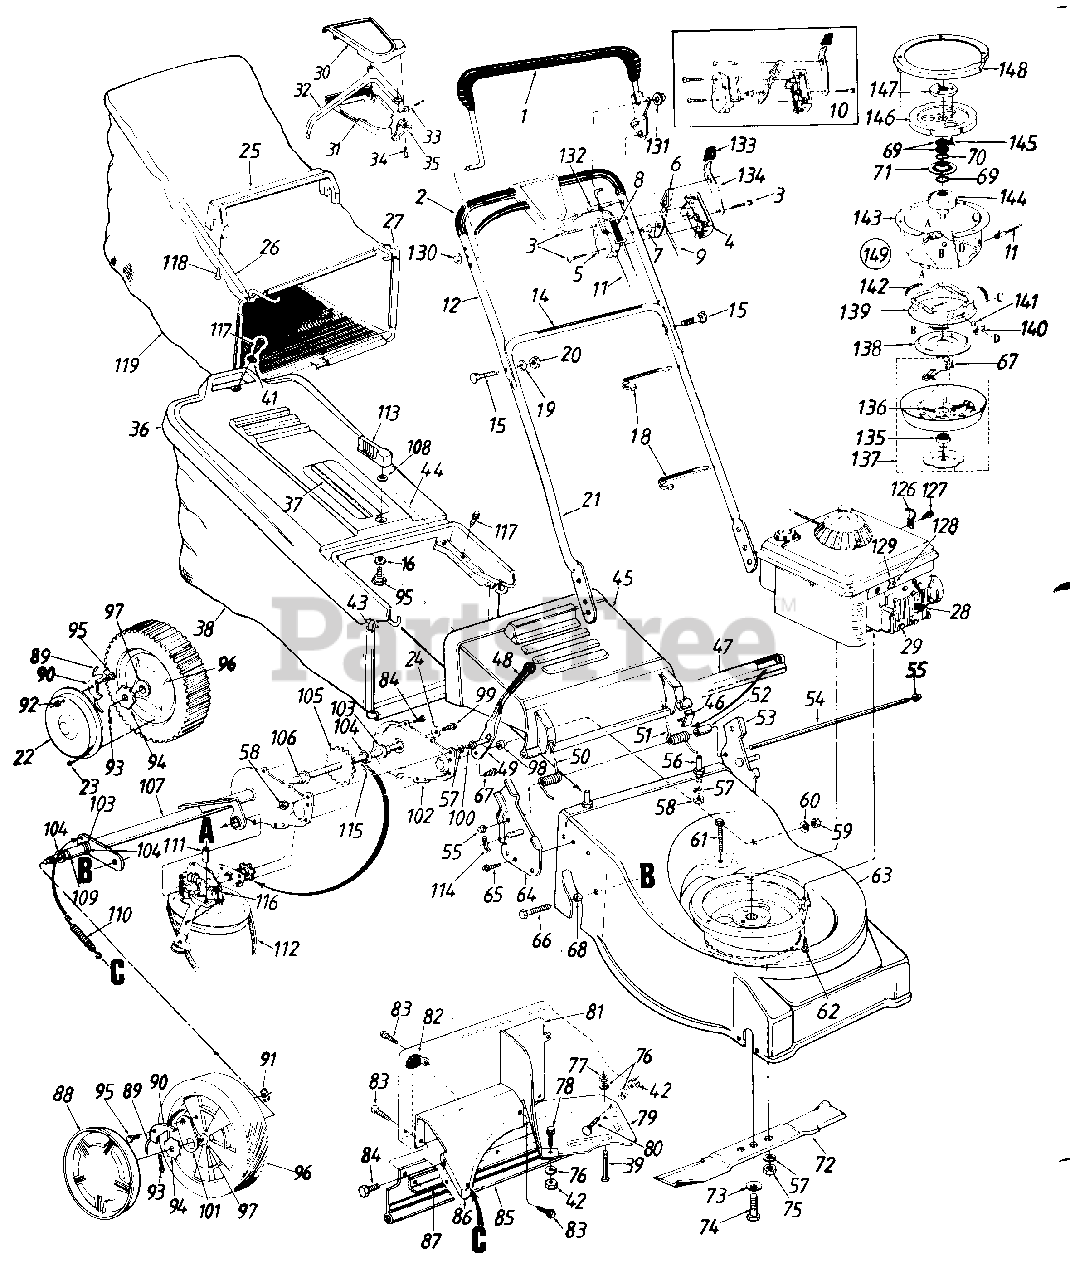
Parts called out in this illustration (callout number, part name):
1	Control Handle Ass'y.
3	Truss Mach. B-Tap Scr. #12 x 1.5" Lg.
4	Control Panel Half
5	Clutch Panel Half
6	Throttle Control Lever
7	Control Disc Pin
8	Control Label-Throttle
9	Throttle Wire-58" Lg.
10	Control Housing Comp.
11	Control Cable-52" Lg.
12	Upper Handle (Painted)
14	Instruction Label-Handle
15	Curved Carriage Bolt 5/16-18 x 1.38" Lg.
16	Bowed Washer
18	Cable Tie
19	L-Wash. 5/16" I.D.
20	Hex Nut 5/16-18 Thd.
21	Lower Handle (Painted)
22	Hub Cap
23	Pan Hd. Tap Scr. #12 x .50" Lg.
24	Bell-Wash. .265" I.D. x .75"
25	Bag Handle
27	Front Catcher Frame
28	Spark Plug Boot
29	Engine
30	Control Cover Half-Upper
31	Control Cover Half-Lower
32	Control Lever
33	Drive Cable-53" Lg.
34	Flat C-Sunk Hd. Tap Scr. #10 x .75" Lg.
35	Cable Mtg. Cap
36	Hardtop Bag Cover
37	Hardtop Handle
38	Grass Bag
39	Truss Mach. Scr. /4-20 x 1.0" Lg.
41	Fl-Wash. .281" I.D. x .62"
42	Hex Nut 1/4-20 Thd.
43	Front Catcher Frame
46	Deflector Plug
47	Seal-Extrusion
49	Spring Lever
50	Torsion Spring-R.H.
51	Torsion Spring-L.H.
52	Spacer.255" I.D.
53	Handle Brkt. Ass'y.-L.H.
54	Hinge Pin 17.75" Lg.
55	Cap Speed Nut
56	Shld. Pin 3/8-24 x 1.43" Lg.
57	L-Wash. 3/8" I.D.
58	Hex Jam Nut 3/8-24 Thd.
59	Hex L-Nut 3/8-24 Thd.
60	Bell-Wash. .38" I.D. x .88"
61	Hex Wash. Hd. Tap Scr. 1/4-20 x 1.5" Lg.
62	Hex L-Wash. Hd. Scr. 3/8-16 x 1.5" Lg.
63	21" Deck Ass'y.
64	Handle Brkt. Ass'y.-R.H.
65	Hex L-Wash. Hd. AB-Tap Scr. 1/4 x .62" Lg.
66	Hex Wash. Hd. Tap Scr. 3/8-16 x .75" Lg.
67	Hex Wash. Hd. Tap Scr. 1/4-20 x .5" Lg.
68	Spacer.383" I.D.
69	Serrated Washer 1.0" I.D.
70	Wave Washer 1.005" I.D.
71	Serrated Pulley Half
72	21" Blade
73	Bell-Wash. .46" I.D. x .88"
74	Hex Bolt 7/16-20 x 2.0" Lg. (Grade 5)
75	Hex Nut 3/8-24 Thd. (Grade 8)
76	L-Wash. 1/4" I.D.
77	Hex Jam Nut 1/4-20 Thd.
78	Hex Bolt 1/4-20 x .85" Lg.
79	Rear Belt Baffle
80	Carr. Bolt 1/4-20 x .50" Lg.
83	Torx Mach. AB-Tap Scr. 1/4 x .62" Lg.
84	Hex B-Tap Scr. 1/4 x .38" Lg.
85	Rear Flap
89	Plastic Spring
90	Pawl.345" I.D.
91	Weld Nut 1/4-20 Thd.
92	Hex Ins. L-Nut 1/4-20 Thd.
93	Cotter Pin 1/8" Dia.
94	Ratchet Wheel 1.62" O.D.
95	Shld. Bolt .342" Dia. x .268"
96	Wheel Ass'y. Comp.-Rear
97	Flange Ball Bearing 1/2" I.D.
98	Shld. Spacer. 50" Dia.
99	Hex Bolt 1/4-20 x .62" Lg. (Grade 5)
100	Shld. Pin 3/8-24 x 1.43" Lg.
101	Pawl Plate
104	Fl-Wash. .531" I.D. x .93"
105	Rear Axle Ass'y.
106	Hex Flange Bearing
109	Spacer. 513" I.D.
110	Extension Spring 3.8" Lg.
111	Spacer.325n I.D.
112	V-Belt
113	Grass Catcher Locking Knob
114	Internal Cotter Pin 5/16" Dia.
115	#48 Chain .50" Pitch x 30 Links
116	Transmission Comp.
117	Hex L-Wash. Hd. AB-Tap Scr. 1/4 x .62" Lg.
118	Hex AB-Tap Scr. #12 x 1.25" Lg.
119	Grass Bag
126	Cable Clamp
127	Hex B-Tap Scr. #10 x .38" Lg.
128	Hex B-Tap Scr. #10 x .62" Lg.
129	Cable Clamp
130	Push Cap
131	Push Cap
132	Lock Pin .314" Dia. x 1.75
133	Spring Lever Knob
134	Lockout Spring
135	Ball Brg. .669" I.D. x 1.574"
136	Cornp. Spring .35" O.D. x 2.0" Lg.
137	Clutch Blade Housing Ass'y.
138	Clutch Cone
139	Brake Cup Cone
140	Ball Block
141	Steel Ball .50" Dia.
142	Ext. Spring 1.75" Lg.
143	Clutch Housing
144	Fixed Pulley Adapter
145	Flat Hd. Tap Scr. 1/4-20 x .625" Lg.
146	Flywheel
147	Flywheel Adapter
148	Engine Mounting Plate Cover
149	Blade Brake Clutch Ass'y. Comp.
